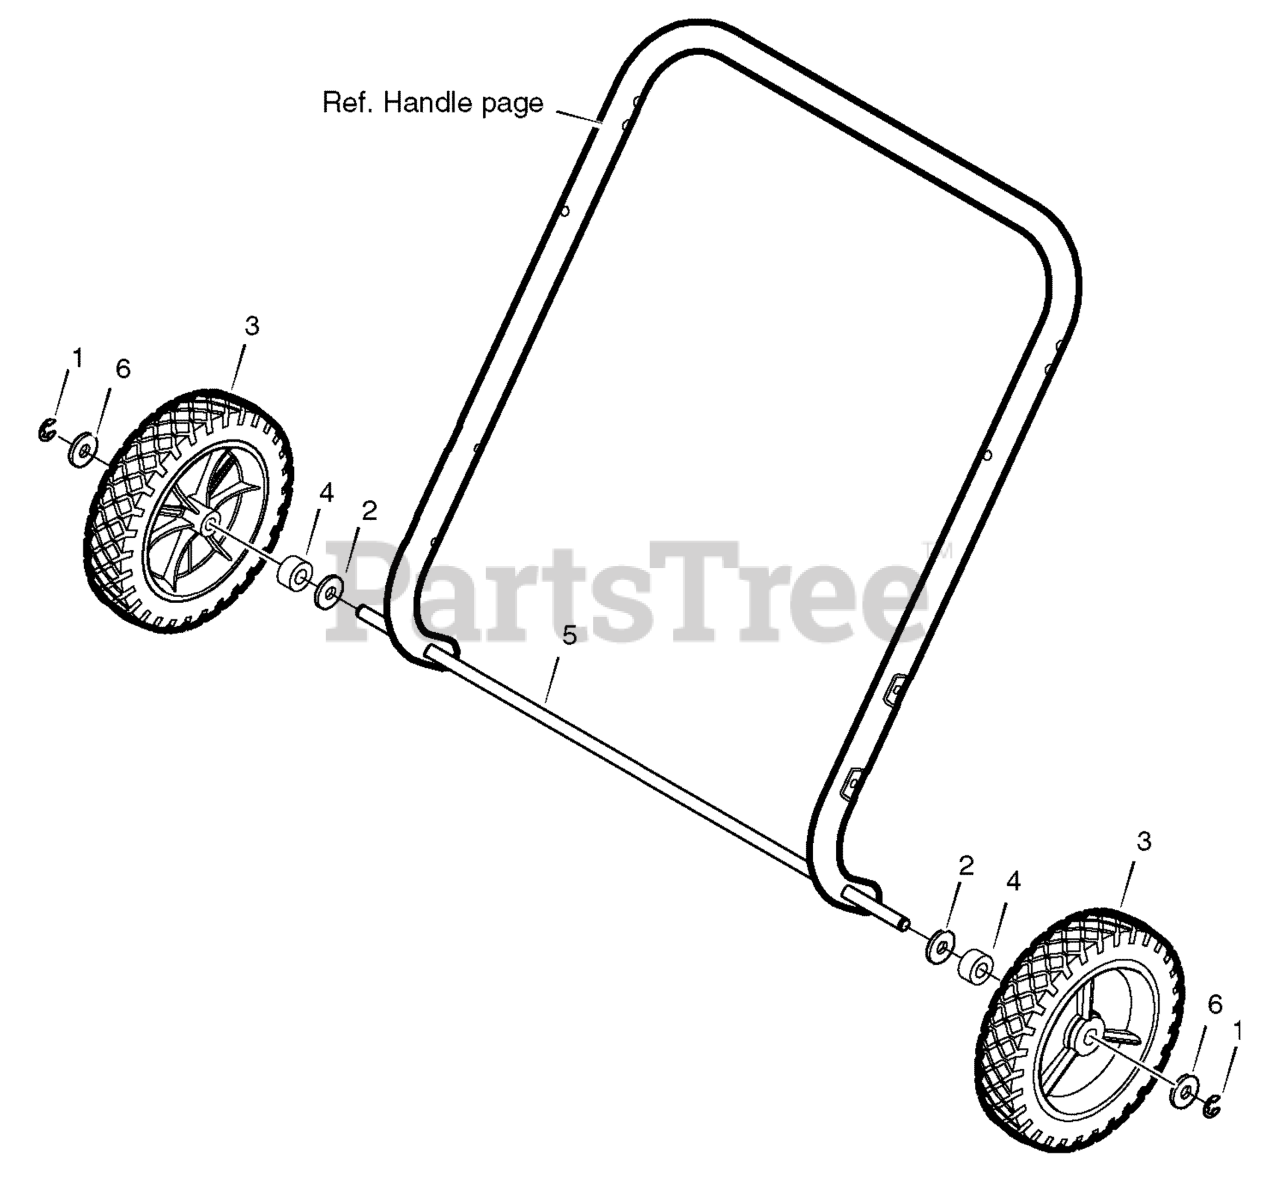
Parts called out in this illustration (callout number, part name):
1	Retainer, E-Ring
2	Washer
3	Wheel and Tire 7" x 1.50"
4	Sleeve, Spacer
5	Rod, Axle
6	Washer
